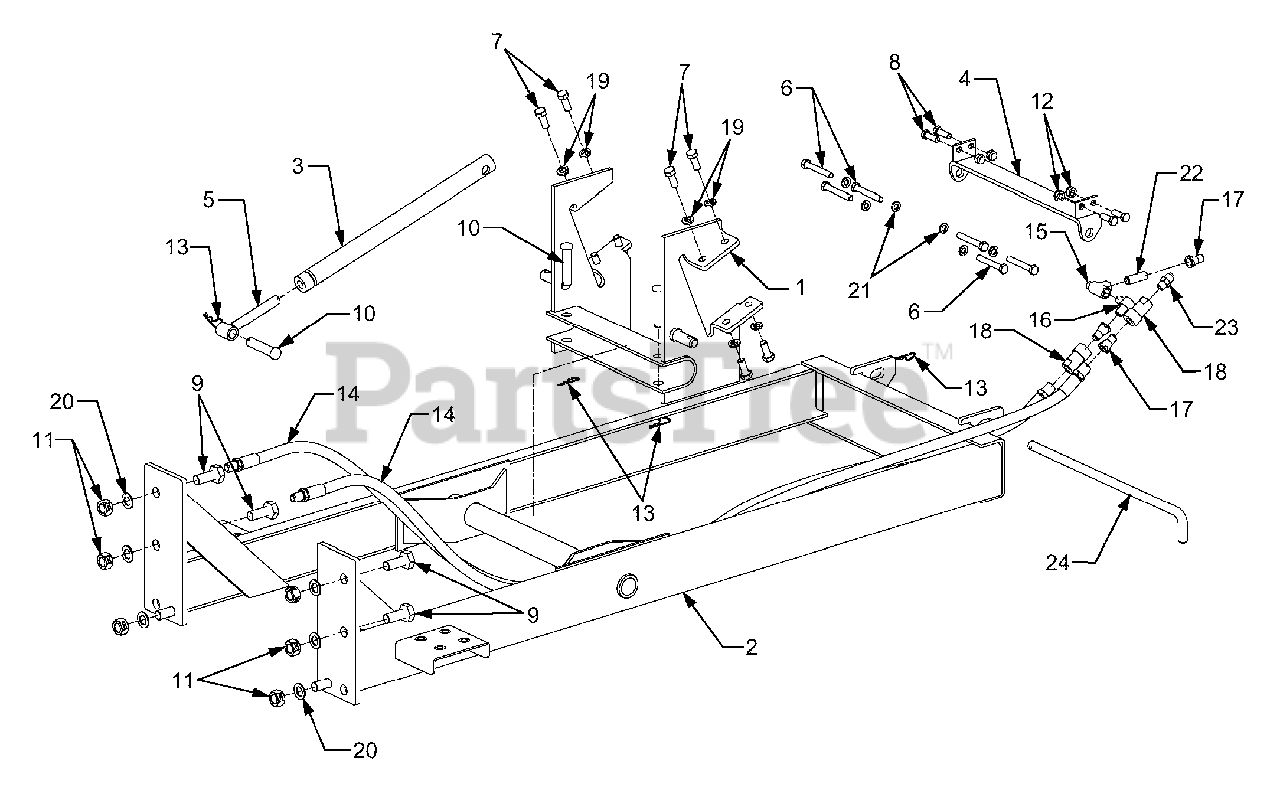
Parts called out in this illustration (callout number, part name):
1	Bracket, Backhoe Mounting
2	Frame, Backhoe
3	Link, Top Adjustment
4	Bracket, Front Mounting
5	Rod, Top Link Adjustment
6	Screw, Hex Cap, M12-1.75 x 80 GR8.8
7	Screw, Hex Cap, M14-2.0 x 35 GR8.8
8	Screw, Hex Cap, M12-1.75 x 35 GR8.8
9	Screw, Hex Cap, M20-1.5 x 50
10	Pin, Clevis, 19mm x 84mm
11	Nut, Hex Center Lock, M20 x 1.5
12	Nut, Hex Flange Lock, M12 x 1.75
13	Pin, Internal Cotter
14	Hose, Hydraulic, 1/2ID x 100
15	Fitting, Tee, 3/8-18
16	Fitting, Elbow - Male
17	Coupling, Hydraulic - Male
18	Coupling, Hydraulic - Female
19	Washer, Lock, 9/16
20	Washer, Flat, .812 x 1.38 x .1
21	Washer, Lock, 1/2
22	Pipe, Straight, 3/8 NPT x 2.0
23	Fitting, Adapter - Male
24	Rod, Backhoe Pin
